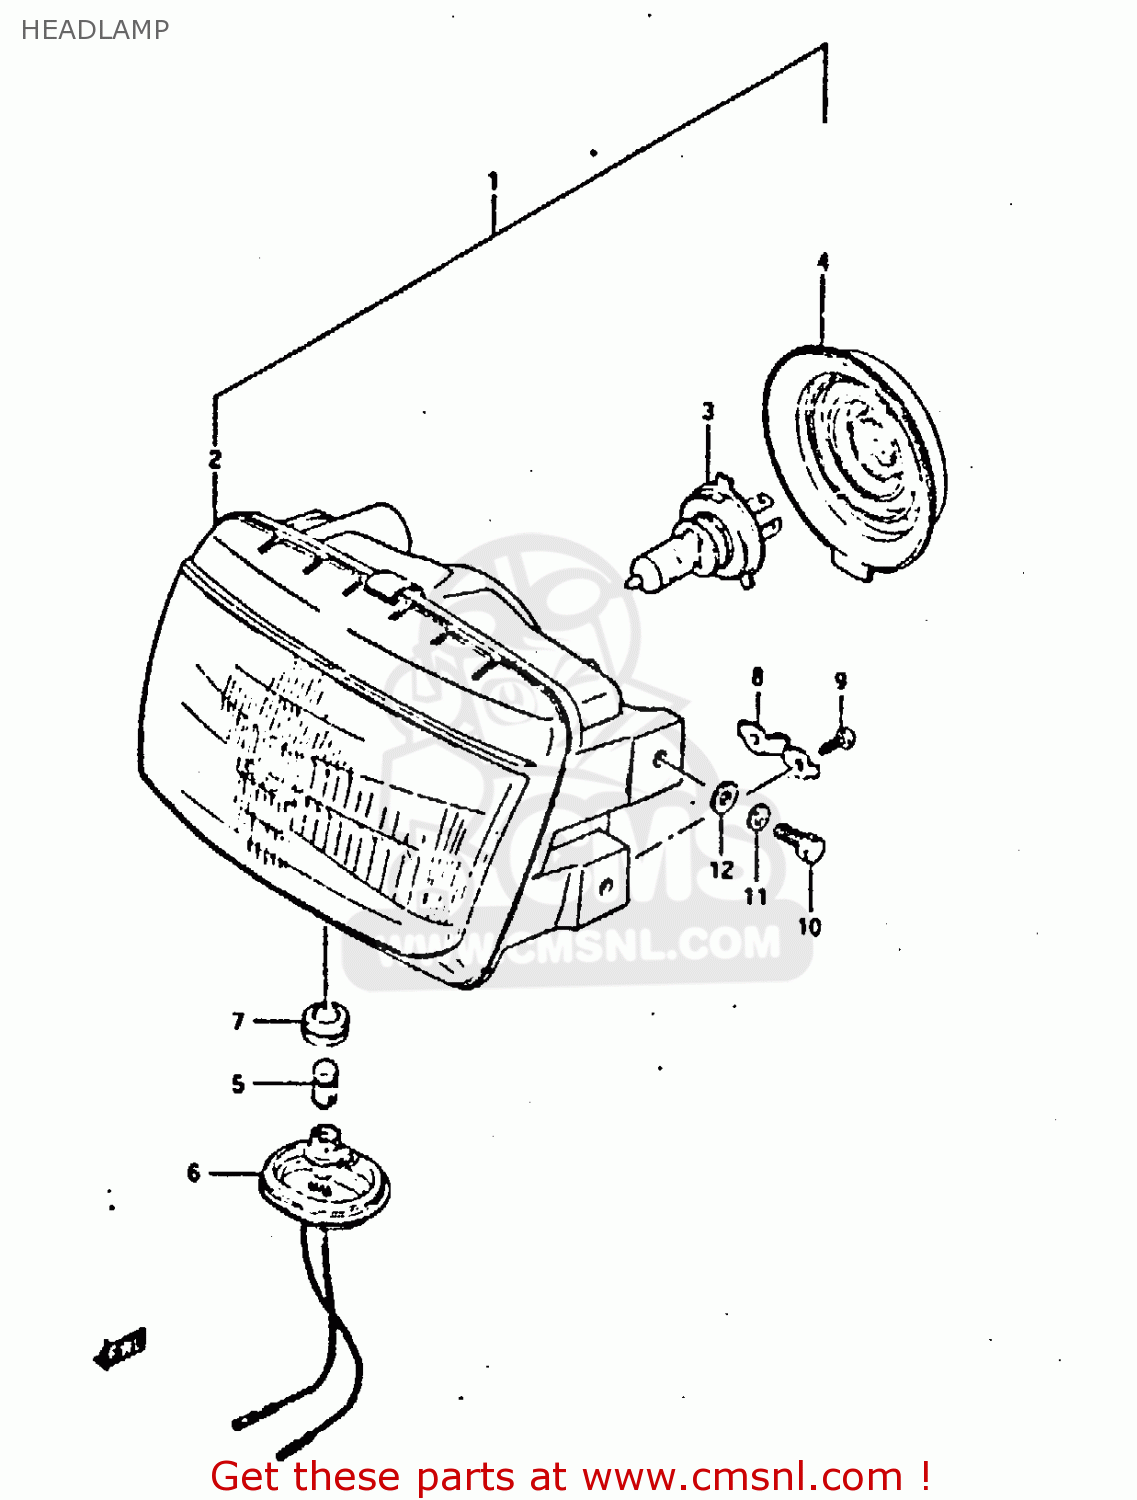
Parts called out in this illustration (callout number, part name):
1	HEADLAMP GSX 40
2	HEADLAMP ASSY
3	BULB(12V60/55W,H4)
4	COVER,SOCKET
5	BULB(12V3.4W,STANLEY,A72A)
6	SOCKET
7	JOINT,RUBBER
9	SCREW
10	BOLT
11	WASHER,LOCK
12	WASHER, LOWER
